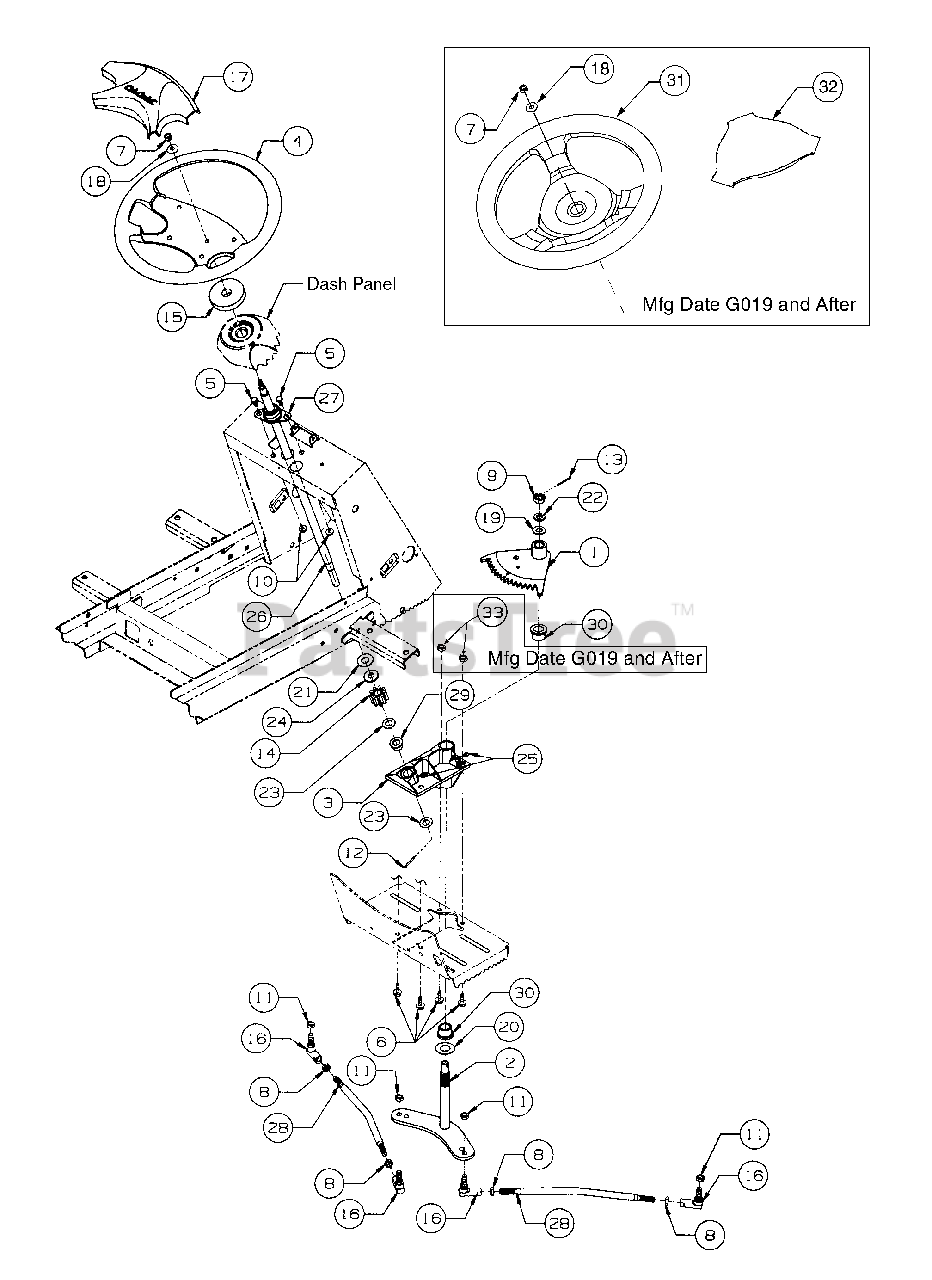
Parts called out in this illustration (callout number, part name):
1	Segment Assy, 18T Steering
2	Arm Assy, Lower Steering
3	Housing Assy,
4	Wheel, Steering
5	Screw, Hex Cap, 1/4 - 20 x .62, GR5
6	Screw, Hx Wsh Hd-TPTT, 5/16-18x.75
7	Nut, Hex Center Lock, 5/16-24
8	Nut, Hex Jam, 3/8-24 GR5
9	Nut, Hex Slotted, 1/2-20 GR5
10	Nut, Hex Flange Lock, 1/4-20
11	Nut, Hex Lock, 3/8-24 GR5
12	Pin, Cotter, 1/8 Dia x 1
13	Pin, Cotter, 3/32 Dia x 1.25
14	Pinion, Steering
15	Gasket, Steering
16	Joint, Ball, 3/8-24
17	Insert, Steering Wheel
18	Washer, Bell, .340 x .88 x .06 Thk
19	Washer, Flat, .510 x 1 x .06 Thk
20	Washer, Flat, .760 x 1.5 x .03 Thk
21	Washer, Flat, .56 x 1 x .04 Thk
22	Washer, Lock, 1/2
23	Washer, Flat, .531 x 1 x .027 Thk
24	Wshr, Rubber Flat, .50 x 1.12 x .125 Thk
25	Fitting, Grease, 3/16 Drive Type
26	Shaft, Steering
27	Bearing, Flange
29	Bearing, Flange, .503 ID
30	Bearing, Bronze Flange, .75 ID
31	Wheel, Steering, Soft Grip
32	Insert, Steering Wheel Cover
33	Nut, Hex Center Lock, 5/16-18
